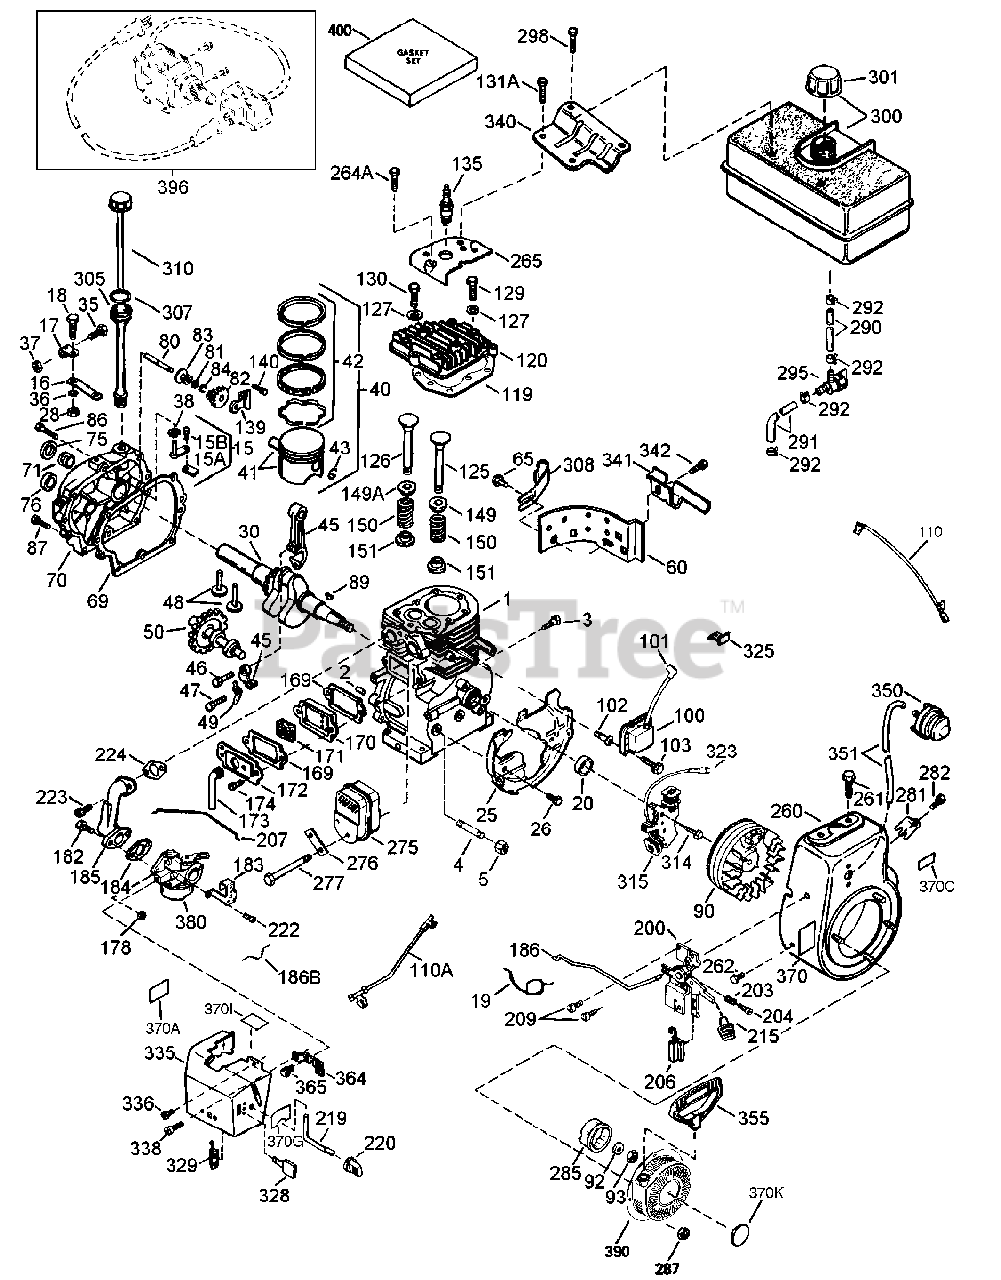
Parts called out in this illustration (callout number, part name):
1	Cylinder
2	Dowel Pin
3	Scrw, 1/4-20 x 1/2"
4	Oil Drain Extension
5	Extension Cap
15	Governor Rod
15A	Governor Yoke
15B	Screw, 6-40 x 5/16"
16	Governor Lever
17	Governor Lever Clamp
18	Screw, Torx T-15, 8-32 x 3/8"
19	Speed Control Spring
25	Blower Housing Baffle
26	Screw, 1/4-20 x 5/8"
28	Lock Nut, 10-32
30	Crankshaft
35	Screw, 10-32 x 3/4"
36	Lock Washer
37	Lock Nut, 10-32
38	Retaining Ring
40	Piston, Pin & Ring Set (Standard)
41	Piston & Pin Ass'y (Standard)
42	Ring Set (Standard)
43	Piston Pin Retaining Ring
45	Connecting Rod Ass'y
47	Connecting Rod Bolt
48	Valve Lifter
49	Oil Dipper
50	Camshaft (MCR)
60	Blower Housing Extension
65	Screw, 10-24 x 1/2"
69	Cylinder Cover Gasket
70	Cylinder Cover
71	Crankshaft Bushing
80	Governor Shaft
82	Governor Gear Ass'y
83	Governor Spool
84	Retaining Ring
86	Screw, 1/4-20 x 1-3/16"
87	Screw, 1/4-20 x 1-11/16"
89	Flywheel Key
92	Lock Washer
93	Flywheel Nut
100	Solid State Ignition
101	Spark Plug Cover
102	Solid State Mounting Screw
103	Screw, Torx T-15, 10-24 x 15/16"
110	Ground Wire
110A	Ground Wire
119	Cylinder Head Gasket
120	Cylinder Head
125	Exhaust Valve (Standard)
126	Intake Valve (Standard)
129	Screw, 5/16-18 x 1-3/4"
130	Screw, 5/16-18 x 1-1/2"
131A	Screw, 5/16-20 x 5/8"
135	Resistor Spark Plug (J8C/356)
139	Governor Gear Bracket
140	Screw, 10-24 x 1/2"
149	Valve Spring Cap
149A	Valve Spring Cap
150	Valve Spring
151	Valve Spring Keeper
169	Valve Cover Gasket
170	Breather Body
171	Breather Element
172	Valve Cover
173	Breather Tube
174	Screw, 10-24 x 1/2"
178	Nut and Lock Washer, 1/4-28
182	Screw, 1/4-20 x 1"
183	Choke Bracket
184	Carb. to Intake Pipe Gasket
185	Intake Pipe
186	Governor Link
186B	Choke Spring
200	Control Bracket
203	Compression Spring
204	Screw, Torx T-10, 5-40 x 7/16"
207	Throttle Link
209	Screw, 10-32 x 1/2"
215	Control Knob
219	Choke Rod
220	Choke Knob
222	Screw, 10-32 x 1/2"
223	Screw, Torx T-30, 5/16 -18 x 1-1/8"
224	Intake Pipe Gasket
260	Blower Housing
261	Screw, 5/16-18 x 3/4"
262	Screw, Torx T-40, 5/16-24 x 21/32"
264A	Screw, 1/4-20 x 5/8"
265	Cylinder Head Cover
276	Locking Plate
277	Screw, 5/16-18 x 4-3/16"
281	Starter Bubble Cover
282	Screw, 8-32 x 3/8"
285	Starter Cup
287	Nut & Lock Washer, 1/4 -28
290	Fuel Line
291	Fuel Line
292	Fuel Line Clamp
295	Fuel Shut-Off Valve
300	Fuel Tank
301	Fuel Cap
305	Oil Fill Tube
308	Fill Tube Clip
314	Screw, 1/4-20 x 3/4"
315	Alternator Coil (18 Watt)
325	Wire Clip
328	Key Switch (Push-In)
335	Carburetor Cover
336	Screw, 10-32 x 1/2"
338	Screw, 10-32 x 3/8"
340	Fuel Tank Bracket
341	Fuel Tank Bracket
342	Screw,1/4-20 x 5/8"
350	Primer Ass'y
351	Primer Line
355	Mitten Grip Starter Handle
364	Carburetor Cover Bracket
365	Screw, 8-32 x 27/64"
370	Identification Decal
370A	Instruction Decal
370C	Primer Decal
370G	Instruction Decal
370I	Warning Decal
370K	Starter Decal
380	Carburetor
390	Rewind Starter
396	Electric Starter
400	Gasket Set,
